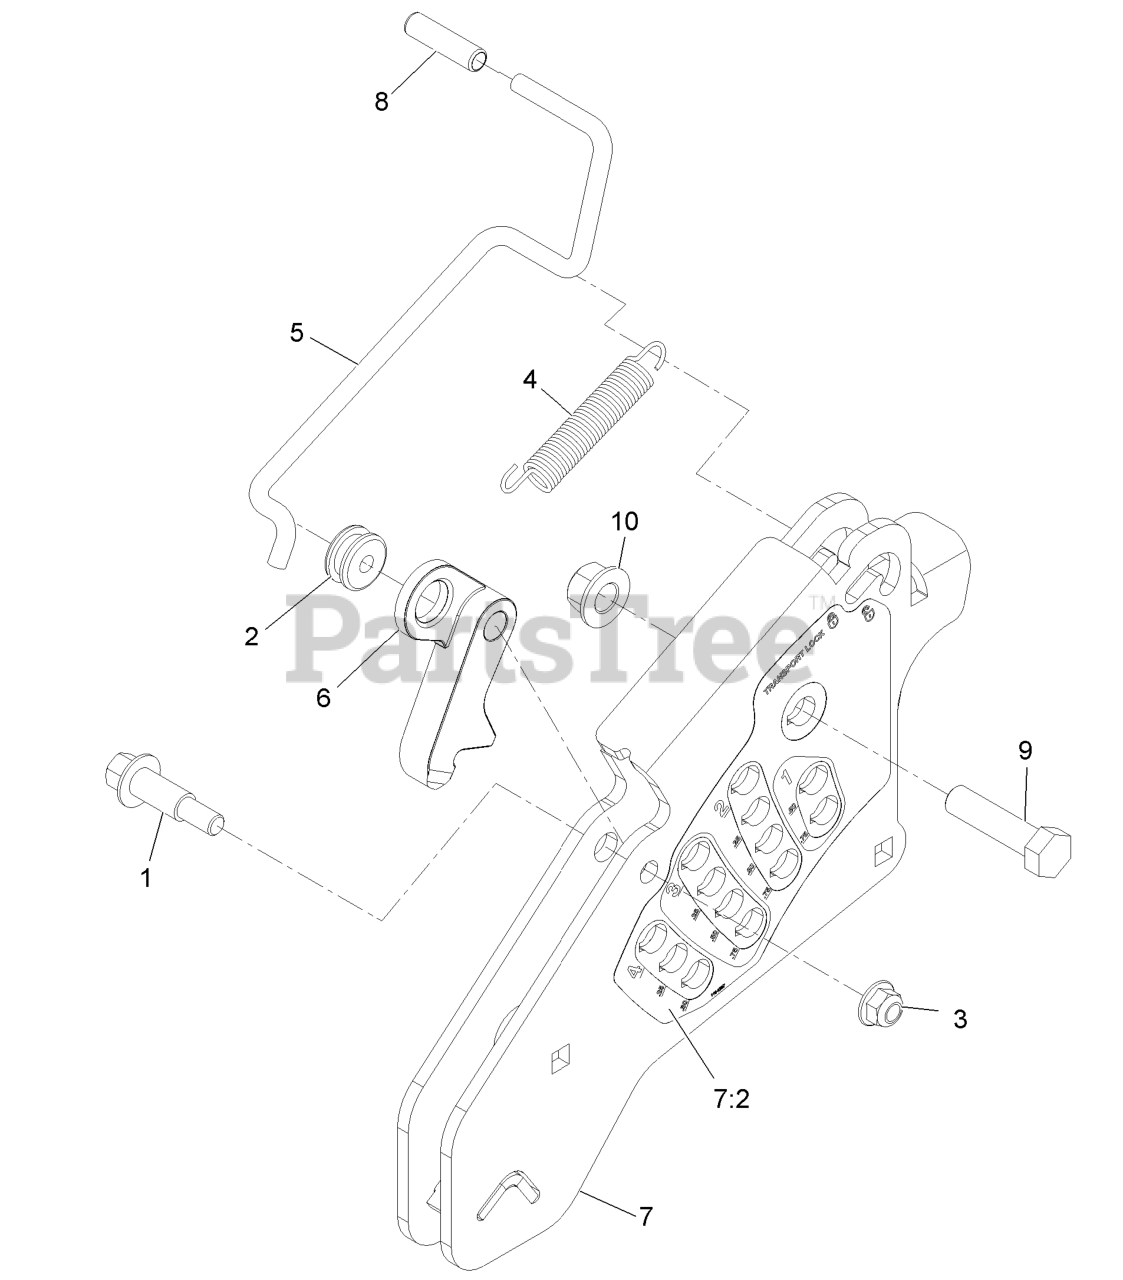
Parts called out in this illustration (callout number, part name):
1	BOLT-SHOULDER
2	GROMMET
3	NUT-HF, NI
4	SPRING-EXTENSION
5	ROD-LOCK, TRANSPORT
6	PAWL-TRANSPORT, HOC
7	HOC PLATE ASM
7:2	DECAL-HOC
8	GRIP-LEVER
9	SCREW-HH
10	Nut-Lock 1/2-13
